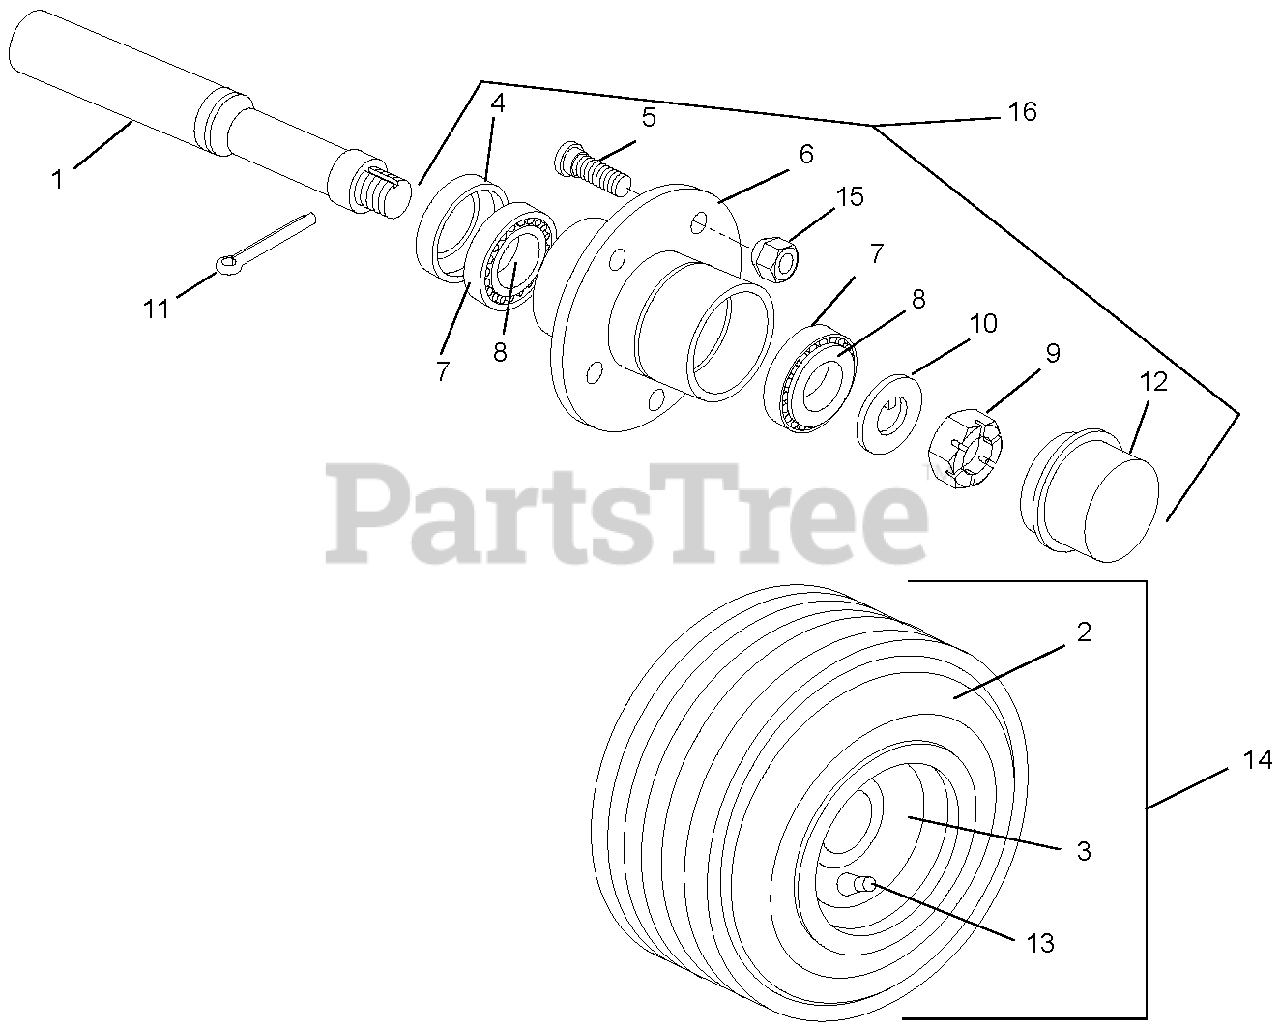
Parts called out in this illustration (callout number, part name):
1	Axle 10.00
2	Tire, Ribbed 18 x 8.5 x 8
3	Wheel, 8 x 7, 5-Hole
5	Bolt, Lug .50-20 x 1.875
6	Hub, Includes Bolts and Bearing Cup
7	Cup, Bearing 1.9687 O.D. x .420
8	Cone, Bearing 1.000 Bore x .5
9	Nut, Hex .75-16 CP Castellated
10	Washer, Axle Left
11	Pin, Cotter .125 x 1.25
12	Cap, Hub
13	Valve Stem, TR-412
14	Tire And Wheel Assembly 18 x 8.5 x 8
15	Nut, Hex Hub .50-20 UNF
16	Hub Assembly, 5-Bolt
